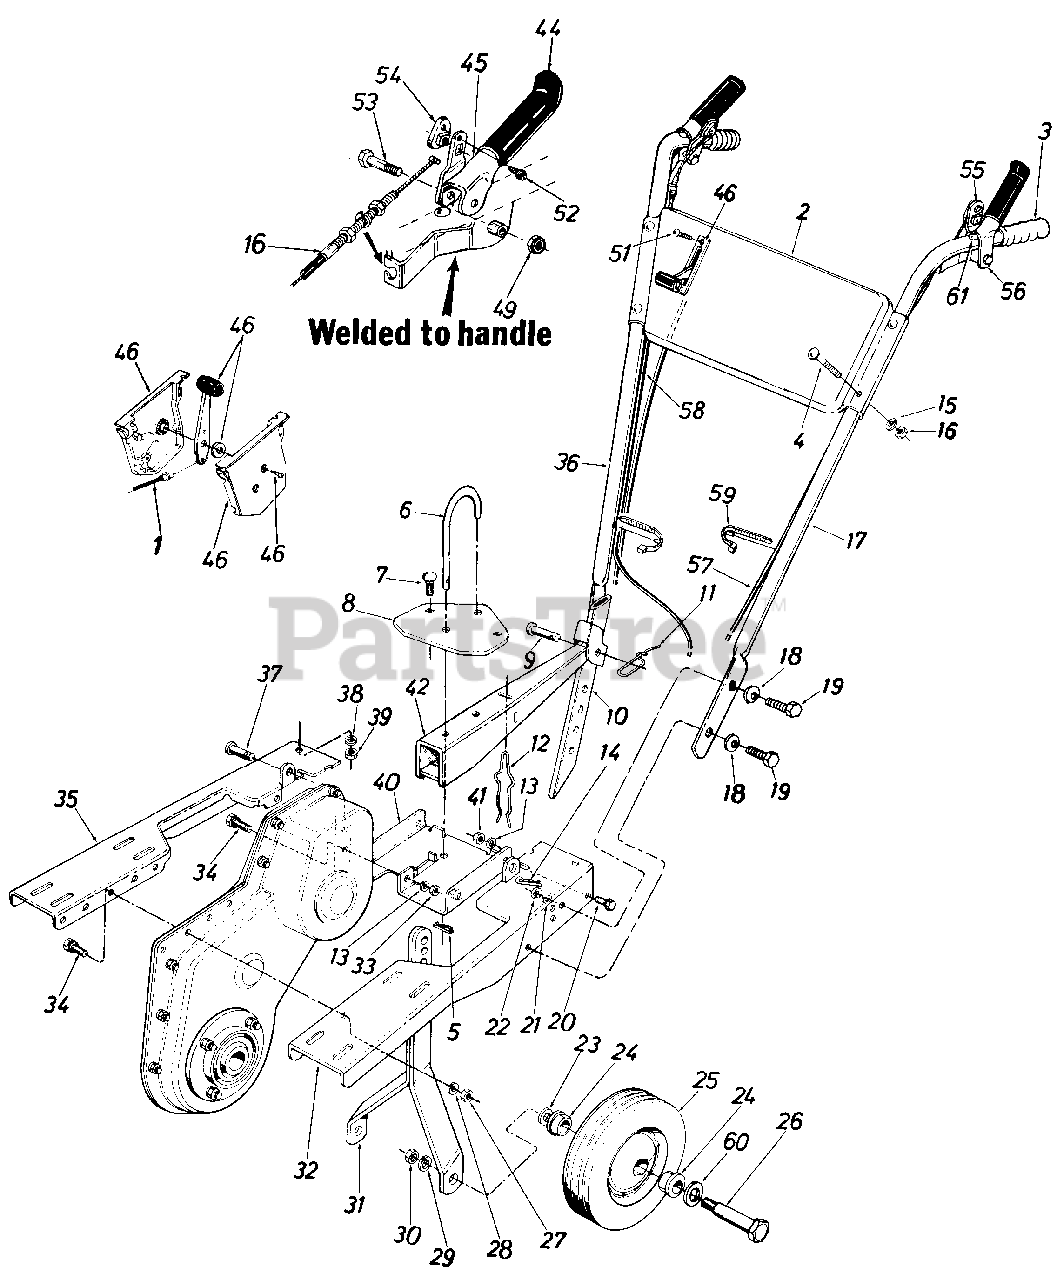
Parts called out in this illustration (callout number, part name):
1	Throttle Control Wire-35"
2	Handle Panel Ass'y.
3	Handle Grip
4	Carriage Bolt 5/16-18 x 1.75"
5	Internal Cotter Pin
6	"U"-Clevis Pin .500" Dia.
7	Carriage Bolt 5/16-1 8 x .75"
8	"U"-Channel Plate
9	Clevis Pin 1/2" Dia.
10	Depth Bar
11	Spring Pin
12	Depth Bar Spring
13	L-Wash. 5/16" I.D.
14	Internal Cotter Pin
15	L-Wash. 5/16" I.D.*
16	Hex Nut 5/16-18 Thd.
17	Handle-L.H.
18	Belleville Wash. 3/8" I.D.
19	Hex Bolt 3/8-16 x 1.00" Lg.*
20	Hex Bolt 5/16-18 x .75" Lg.
21	L-Wash. 3/8" I.D.
22	Hex Nut 3/8-16 Thd.
23	Belleville Wash. .505 I.D. x 1.00" O.D.
24	Fl. Bearing w/Flats .631 I.D.
25	Wheel Ass'y. Comp. 10 x 1.75
26	Shoulder Bolt .625" Dia. x 2.75" Lg.
27	Hex Nut 5/16-18 Thd.
28	L-Wash. 5/16" I.D.
29	L-Wash. 1/2" I.D.
30	Hex Ins. L-Nut 1/2-20 Thd.
31	Wheel Bracket Ass'y.
32	Engine"U"-Channel Ass'y.-L.H.
33	Hex Nut 5/16-18 Thd.*
34	Hex Sems Bolt 5/16-18 x 1.00" Lg. *
35	Engine"U"-Channel Ass'y.-R.H.
36	Handle-R.H.
37	Clevis Pin .375" Dia.
38	L-Wash. 5/16" I.D.*
39	Hex Nut 5/16-18 Thd.*
40	"U"-Channel Bracket Ass'y.
41	Hex Nut 5/16-18 Thd.*
42	Tailpiece Ass'y.
44	Clutch Vinyl Grip
45	Clutch Grip Ass'y.-R.H.
46	Throttle Control Box Ass'y.
49	Hex Ins. L-Nut 3/8-24 Thd.
51	Self-Tap Scr. #10 x 1/2n Lg.
52	Self-Tap Scr. #10 x .44" Lg.
53	Hex Bolt 3/8-24 x 2.0" Lg.
54	Barrel Cable Hold-Down-R.H.
55	Barrel Cable Hold-Down-L.H.
56	Clutch Grip Ass'y.-L.H.
57	Control Cable
58	Control Cable
59	Cable Tie
60	Fl-Wash. .640 I.D. x 1.24"
61	Plug
